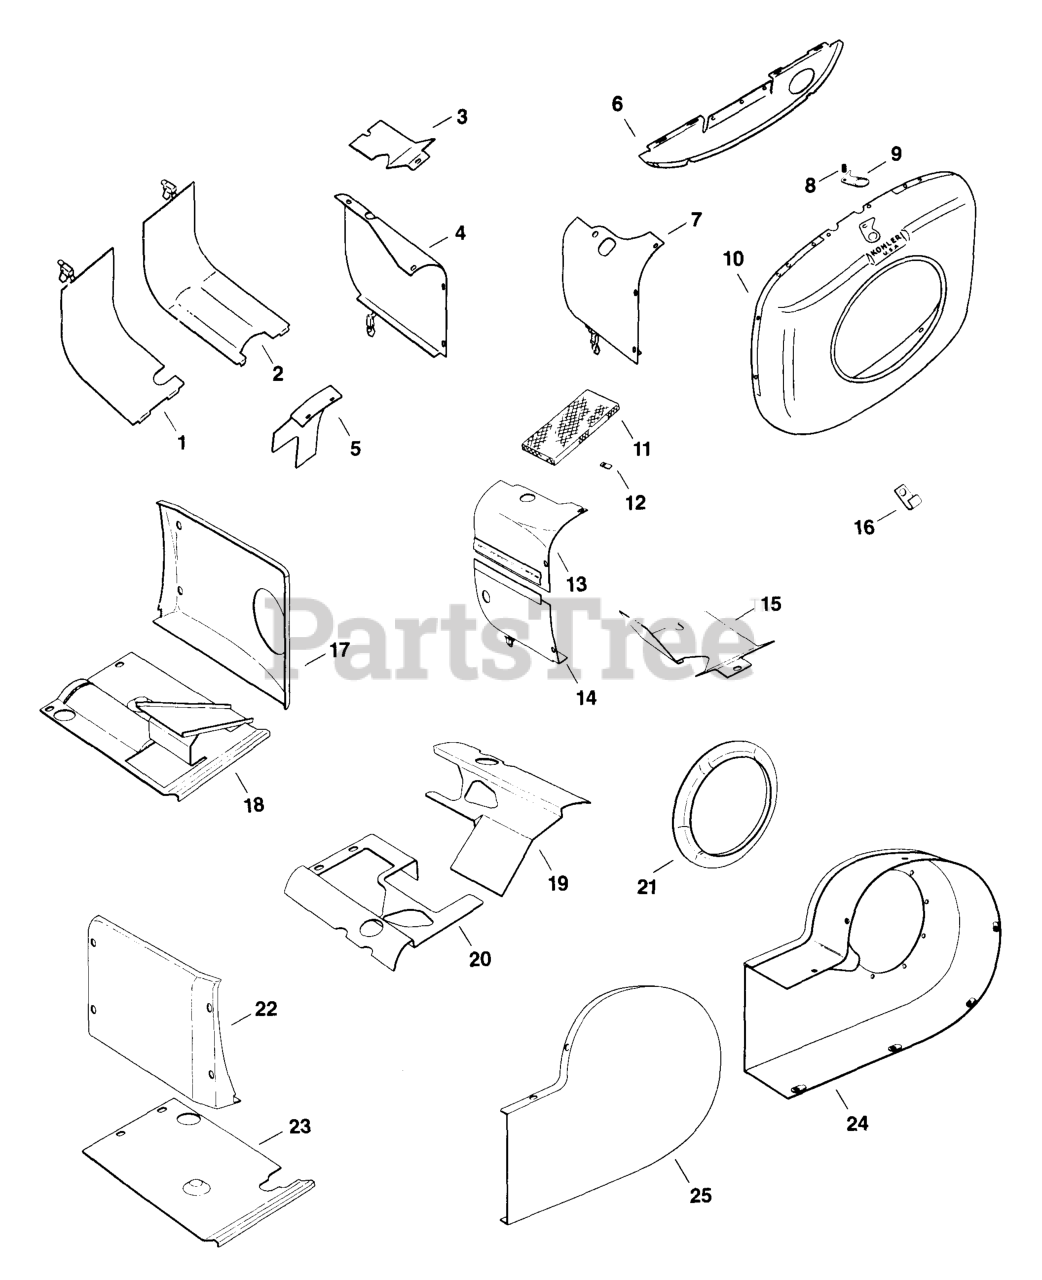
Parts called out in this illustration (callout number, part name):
1	BAFFLE - (#DSC)
2	BAFFLE, CYLINDER #2 - (#DSC)
5	BAFFLE - DISCONTINUED
6	BAFFLE,BLOWER HSG.SUPPORT
7	BAFFLE - (#DSC)
10	KIT, HOUSING
